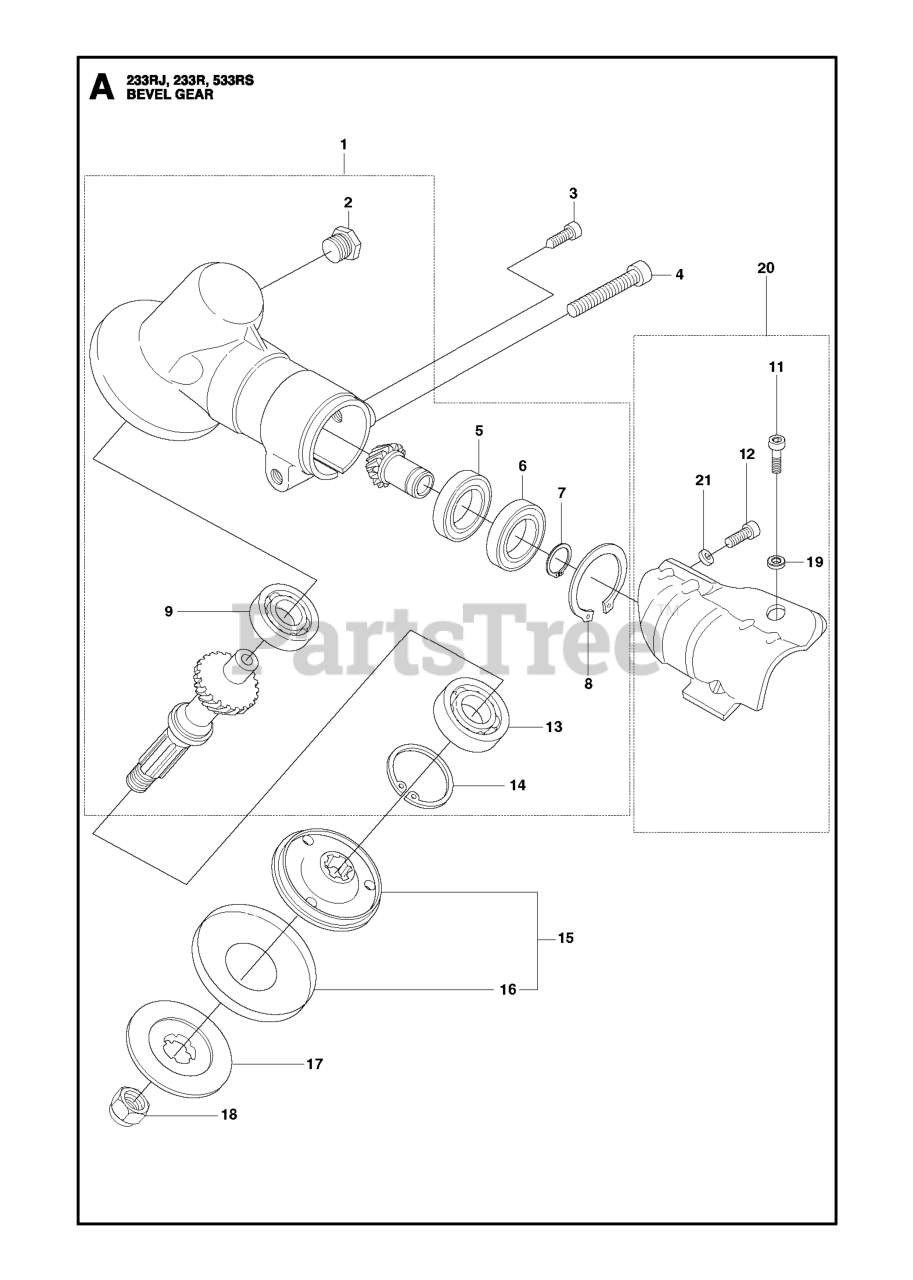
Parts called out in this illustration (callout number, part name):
1	GEARCASE-A
2	PLUG
3	BOLT
4	BOLT
5	BALL BEARING 24X9X1/609ZR
7	RETAINING RING
8	RETAINING RING
9	BALL BEARING 8X22X7/608Z
11	SCREW IHSCM M6X22 10.9 ZN/FE
13	BALL BEARING
14	RETAINING RING SGH 28
15	DRIVE DISC
16	WASHER
17	SUPPORT FLANGE
18	GEARHEAD NUT - BRUSHCUTTER
19	LOCKING NUT M6
21	LOCKING NUT
